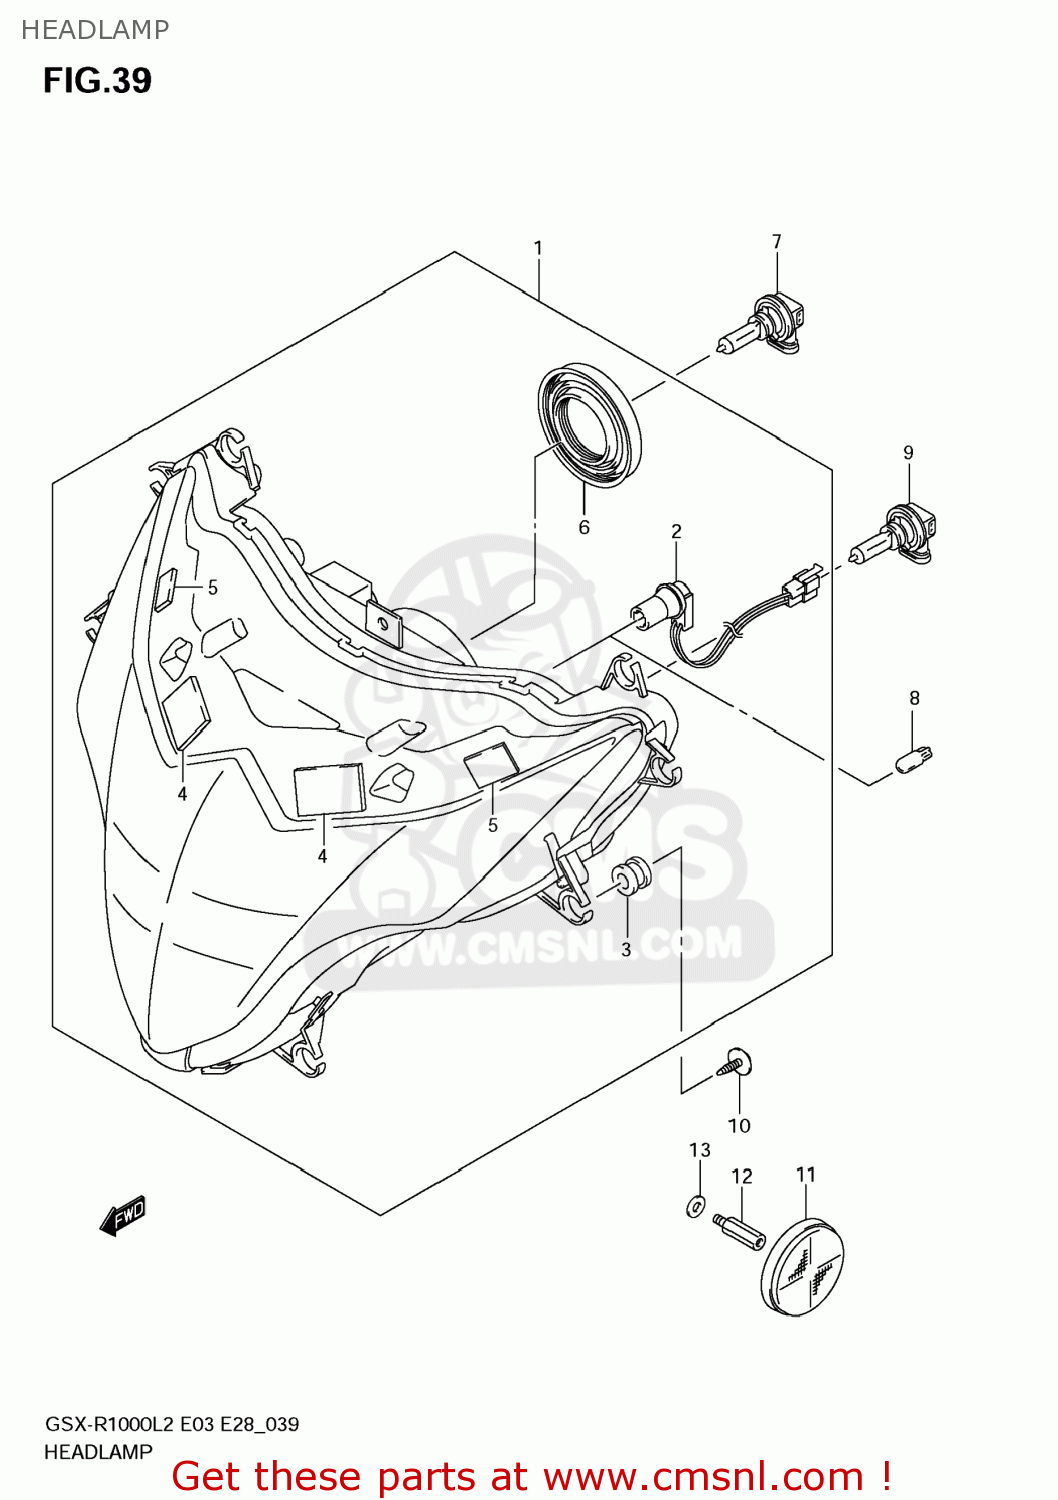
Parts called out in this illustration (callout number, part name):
1	HEADLAMP ASSY
2	CORD ASSY
3	CUSHION
4	FASTENER
5	FASTENER,COWLING
6	COVER,SOCKET
7	BULB(12V55W,H11)
8	BULB(12V5W)
9	BULB(12V65W,H9)
10	SCREW(5X15)
11	REFLEX REFLECTOR ASSY,FR SIDE
12	BOLT
13	WASHER(8.5X18X1)
